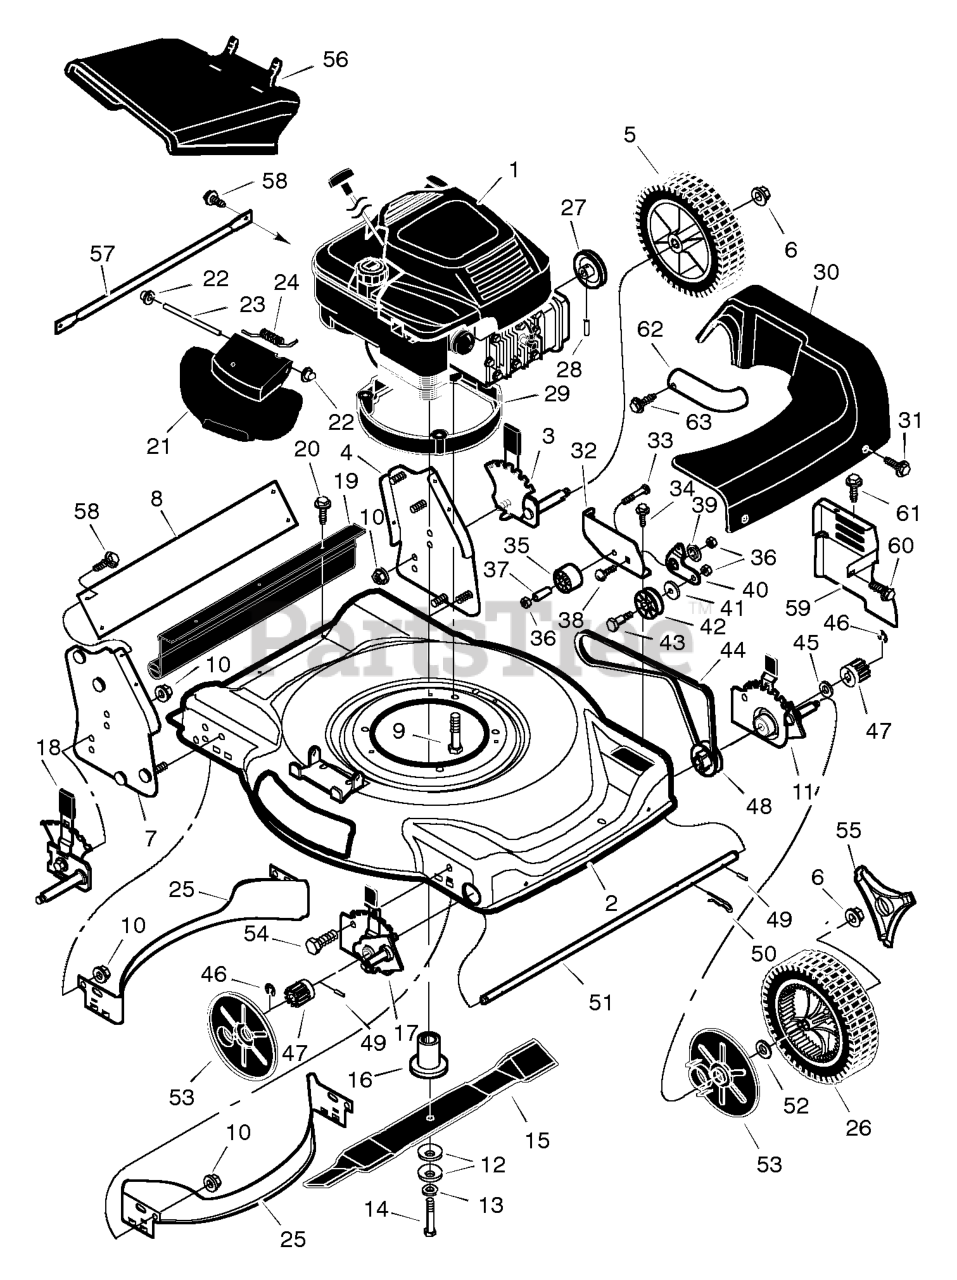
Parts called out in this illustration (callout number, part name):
1	Engine *
2	Housing
3	Height Adjuster, Left Rear
4	Bracket, Left Handle
5	Wheel and Tire, Rear
6	Locknut, Flange
7	Bracket, Right Handle
8	Brace, Handle Bracket
9	Bolt, Engine
10	Nut
11	Height Adjuster, Left Front
12	Washer, Belleville
14	Bolt, Hex
16	Adapter, Blade
17	Height Adjuster, Right Front
18	Height Adjuster, Right Rear
19	Guard, Rear
21	Cover, Mulcher
22	Push- On Cap
23	Pin, Pivot
26	Wheel and Tire, Drive
28	Pin, Spring
29	Base, Engine
30	Cover, Belt
32	Bracket, Idler Support
36	Locknut
37	Bearing
38	Bolt, Carriage
40	Arm, Idler
42	Pulley, Idler
43	Bolt, Shoulder
46	Ring, Retainer
47	Gear, Pinion
49	Pin, Drive
50	Pin, Hair
52	Washer
53	Cover, Dust
54	Bolt
55	Hub Cap
56	Deflector, Chute
59	Shield, Heat
60	Screw
62	Tube, Exhaust
